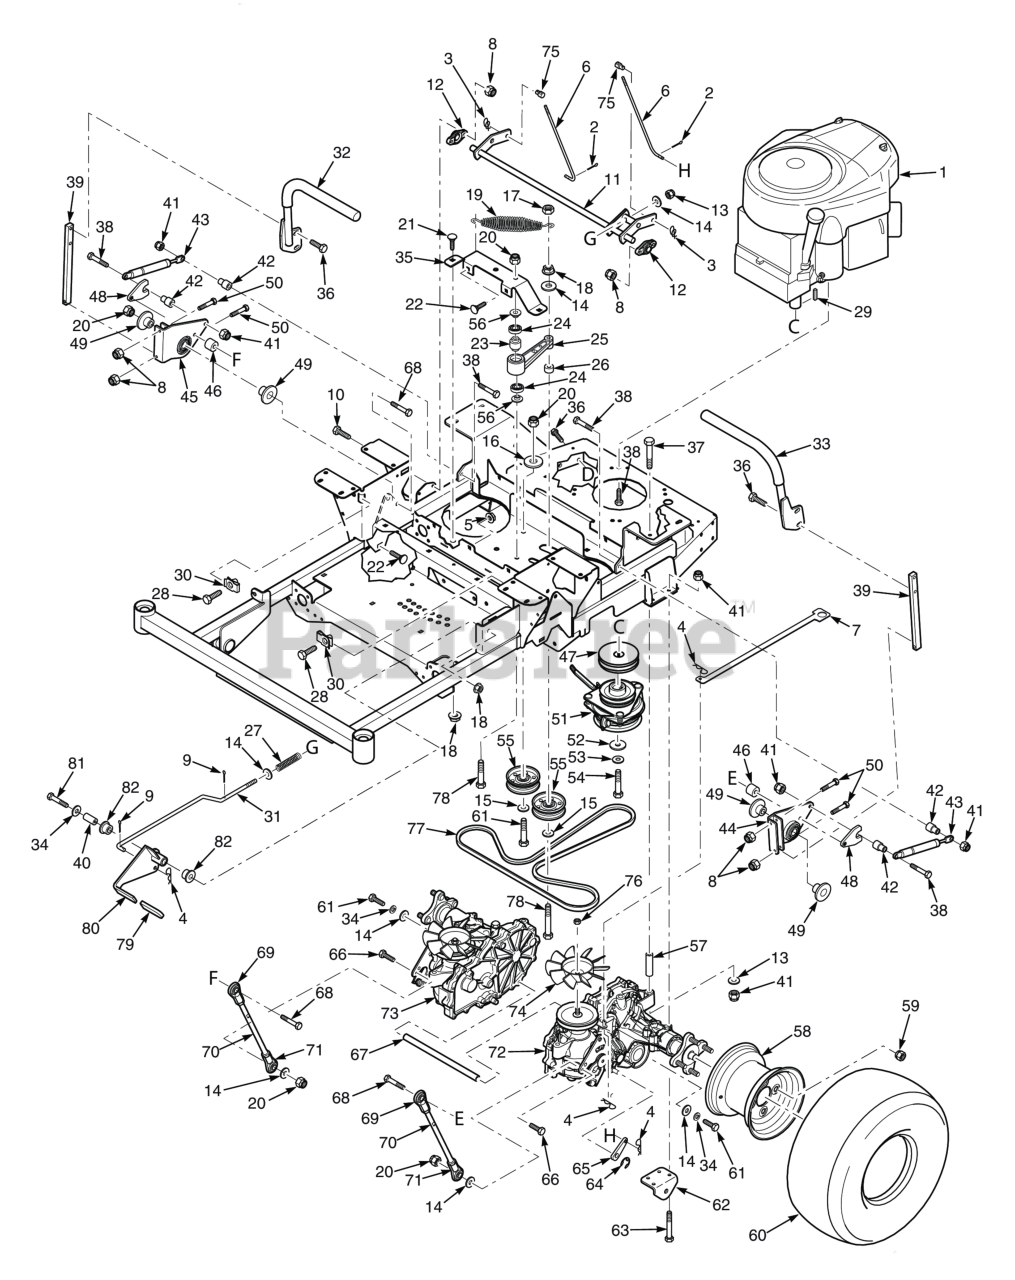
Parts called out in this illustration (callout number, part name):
1	Engine, Kohler 24KT
2	COTTER PIN, 3/32 X 1"
3	Pin, Rue Cotter 3/8" Diameter
4	HAIR PIN, .08 DIAMETER X 1-3/16"
5	Nut, Serrated Flange 5/16-18 (Right Front Engine Mounting, Briggs and Kohler Only)
6	Rod, Brake Adjustment
7	Lever, Dump Valve
8	Nut, Flanged Elastic Stop 1/4-20
9	COTTER PIN, HAIR - 0.94 X 1.62
10	CAP SCREW, 1/4-20 X 1" SERRATED FLANGE HEX
11	Weldment, Brake Lever
12	Bearing
13	Flatwasher, 5/16-.375 x .875 x .083 (35BV & 37BV-EFI)
14	Flatwasher, 3/8" Special (.391 x .938 x .105)
15	Flatwasher, 3/8 (.391 x .938 x .105 HD) Grade 8
16	Flatwasher, 3/8-.406 x 1-1-1/2 x 7 Gauge
17	Bolt, Hex Head 3/8-16 x 1" Ser. Flg.
18	NUT, 3/8-16 SERRATED FLANGE HEX HEAD
19	Spring, Transmission Idler
20	HEX NUT, ELASTIC STOP LOCK, 3/8-16
21	Bolt, Carriage 3/8-16 x 3/4"
22	Bolt, 5/16-18 x .75 RHSN Carriage
23	Spacer, Bearing
24	BEARINGS, BALL, NEUTRAL RETURN
25	Trans. Idler Arm Assy. (Includes 24, 79)
26	Spacer, Idler Pulley - SFZ52
27	Spring, Brake
28	Bolt, Hex Head 3/8-16 x 1-1/4" Special Lock
29	KEY, 1/4 X 1/4 X 3/4"
30	U-Nut, 3/8-16 (short)
31	Rod, Brake Linkage
32	Handle Bar Assembly RH, w/Grip
33	Handle Bar Assembly LH, w/Grip
34	Flatwasher, 3/8" Special (.391 x .938 x .105)
35	Support, Idler Arm
36	Capscrew, 3/8-16 x 1.0" Serrated Flange Hex Hd
37	HEX HEAD BOLT, 5/16-18 X 5"
38	Bolt, Hex Head 5/16-18 x 1-1/2" (Right Front Engine Mounting, Briggs and Kohler Only)
39	Bar, Control Lever
40	Pivot, Brake Lever
41	HEX NUT, ELASTIC STOP LOCK, 5/16-18
42	Spacer, Pump Dampener
43	Damper, Steering
44	Control Link, LH
45	Control Link, RH
46	Spacer, Idler Pulley - SFZ52
47	Pulley, 4-1/2" Dia. 1" Bore
48	Nut, Control Linkage
49	Spacer, Linkage
50	Bolt, Hex Head, 1/4-20 x 1-1/2"
51	Electric Clutch Assembly
52	Flatwasher, 7/16-.469 x 1.75 x .25 (48, 52)
53	Lockwasher, 7/16� Spring
54	Bolt, Hex Head 7/16-20 x 2-1/4" w/Patch (Kawasaki)
55	Pulley, 3-1/2" Dia.
56	Spacer, Controls
57	Spacer, Axle - SFZ52
58	Rim w/Valve Stem
59	Wheel Nut, 1/2-20 x 13/16
60	Wheel Assembly (INCL.58)
61	Capscrew, Hex Head 3/8-16 x 2-1/2"
62	Bracket, Push Arm Link
63	Bolt, Hex Head 5/16-18 x 3.00"
64	Ring, Retaining External .375"
65	Lever, Brake (order through Hydro-Gear)
66	Bolt, Hex Head 3/8-16 x 1-1/2" B&S 32BV
67	Spacer, Axles
68	Capscrew, Hex Head 3/8-16 x 2.0"
69	Rod End, 3/8-24 UNF LH
70	Linkage, Pump
71	Rod End, 3/8-24 UNF RH
72	Transaxle Assy., LH (ZK-KCBC-SLKG-3NTX)
73	Transaxle Assy., RH (ZK-GCBC-SLKF-2NTX)
74	Fan (order through Hydro-Gear)
75	Joint, Swivel
76	Fan Nut (order through Hydro-Gear)
77	Belt, Transmission Drive - SFZ52
78	Capscrew, Hex Head 3/8-16 x 3.25"
79	Grip, Brake Handle
80	Brake Handle Assembly
81	Capscrew, Hex Head 3/8-16 x 2-1/2"
82	Bearing
